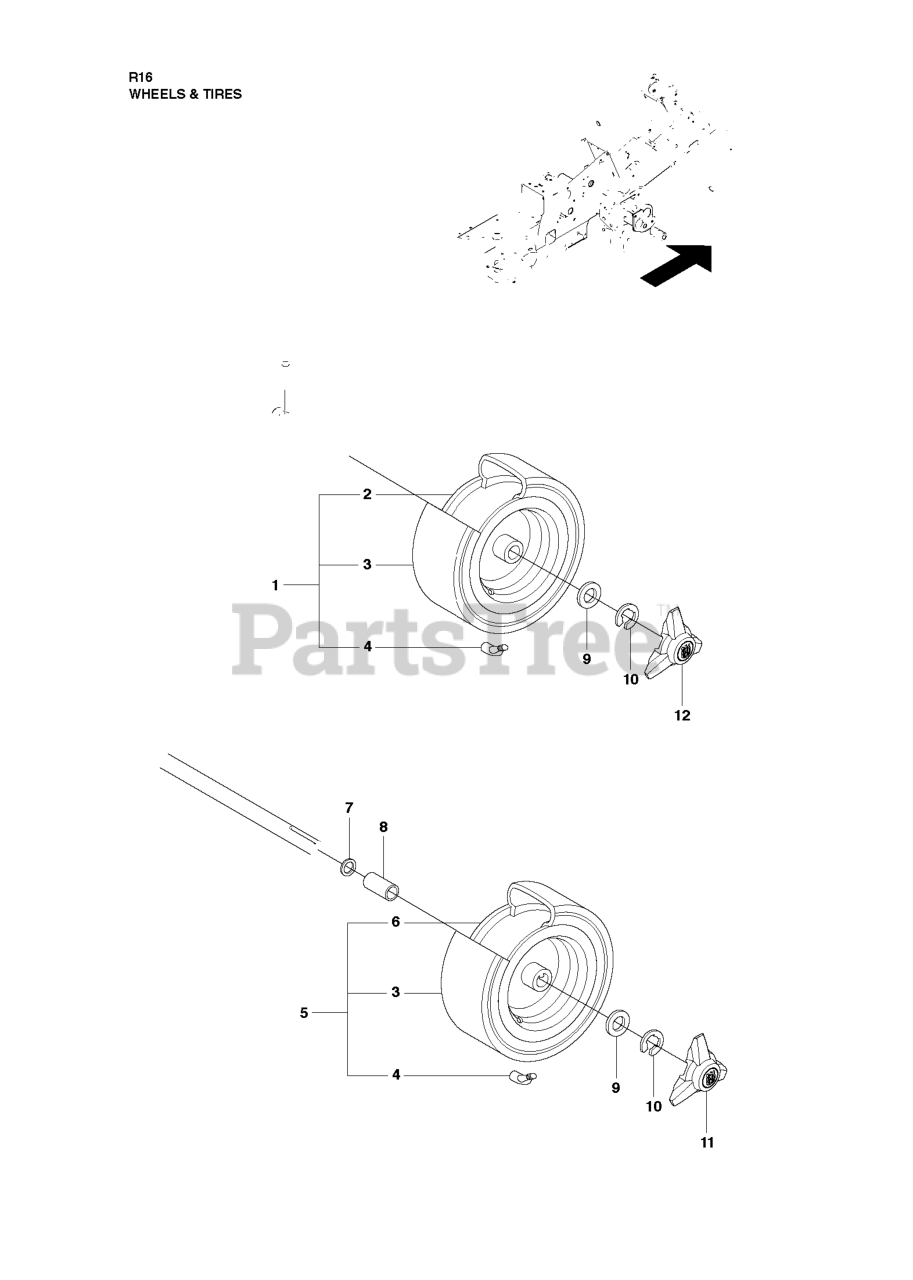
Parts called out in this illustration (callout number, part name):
3	TIRE
4	VALVE
8	SPACE SLEEVE
10	RETAINING RING
